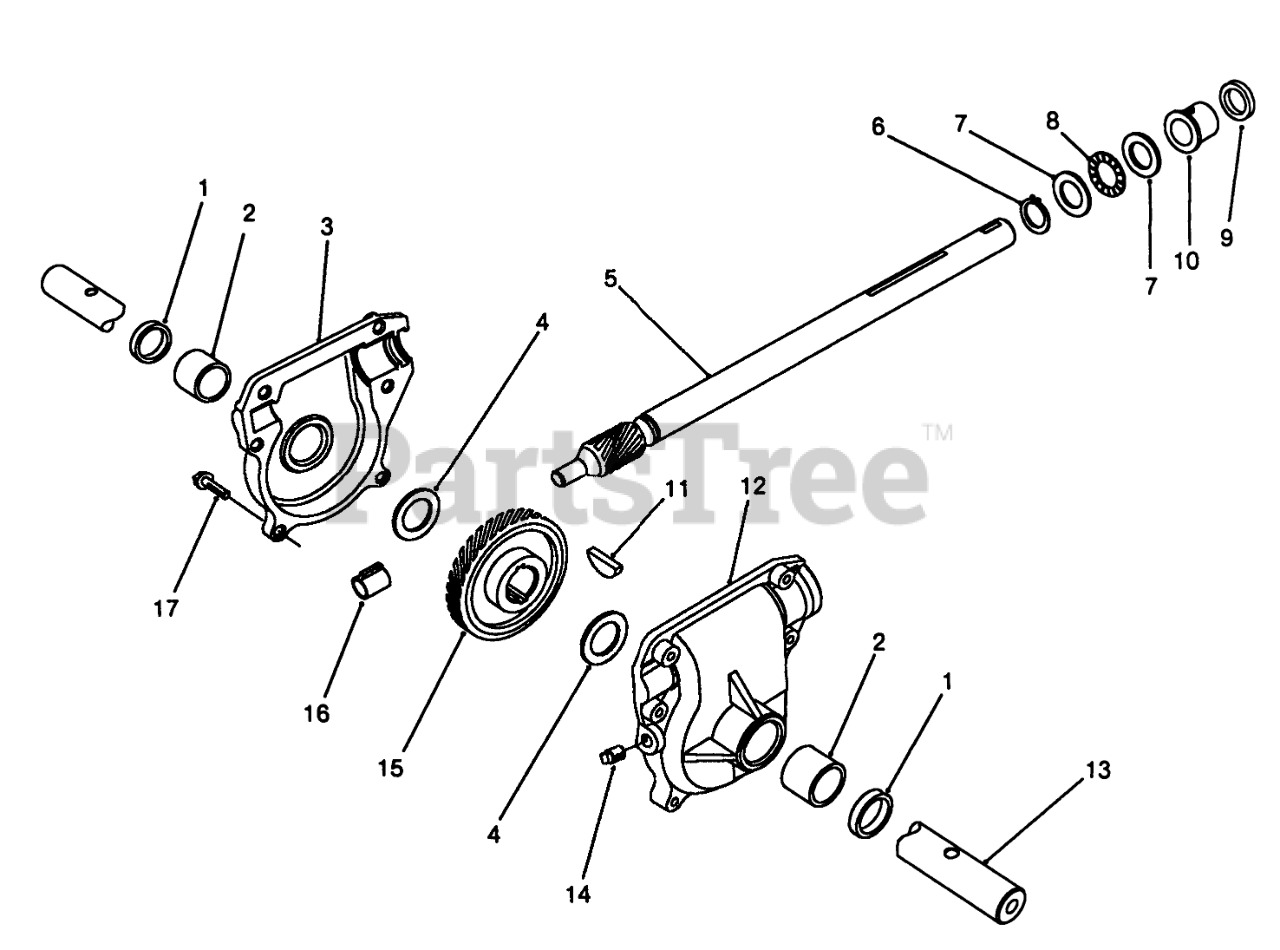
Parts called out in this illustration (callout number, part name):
1	SEAL-OIL
2	BUSHING
3	Gearcase Assembly-R.H. (Incl. Ref. #1-2)
4	WASHER-THRUST
5	Shaft-Impeller
6	RING-RETAINING, Ext
7	WASHER-THRUST
8	BEARING-THRUST
9	SEAL-OIL
10	BUSHING-INPUT
11	KEY-WOODRUFF
12	Gearcase Assembly-L.H. (Incl. Ref. #1-2)
13	SHAFT-AUGER
14	PLUG-PIPE, SQH
15	GEAR-HELICAL
16	BUSHING-WORM
